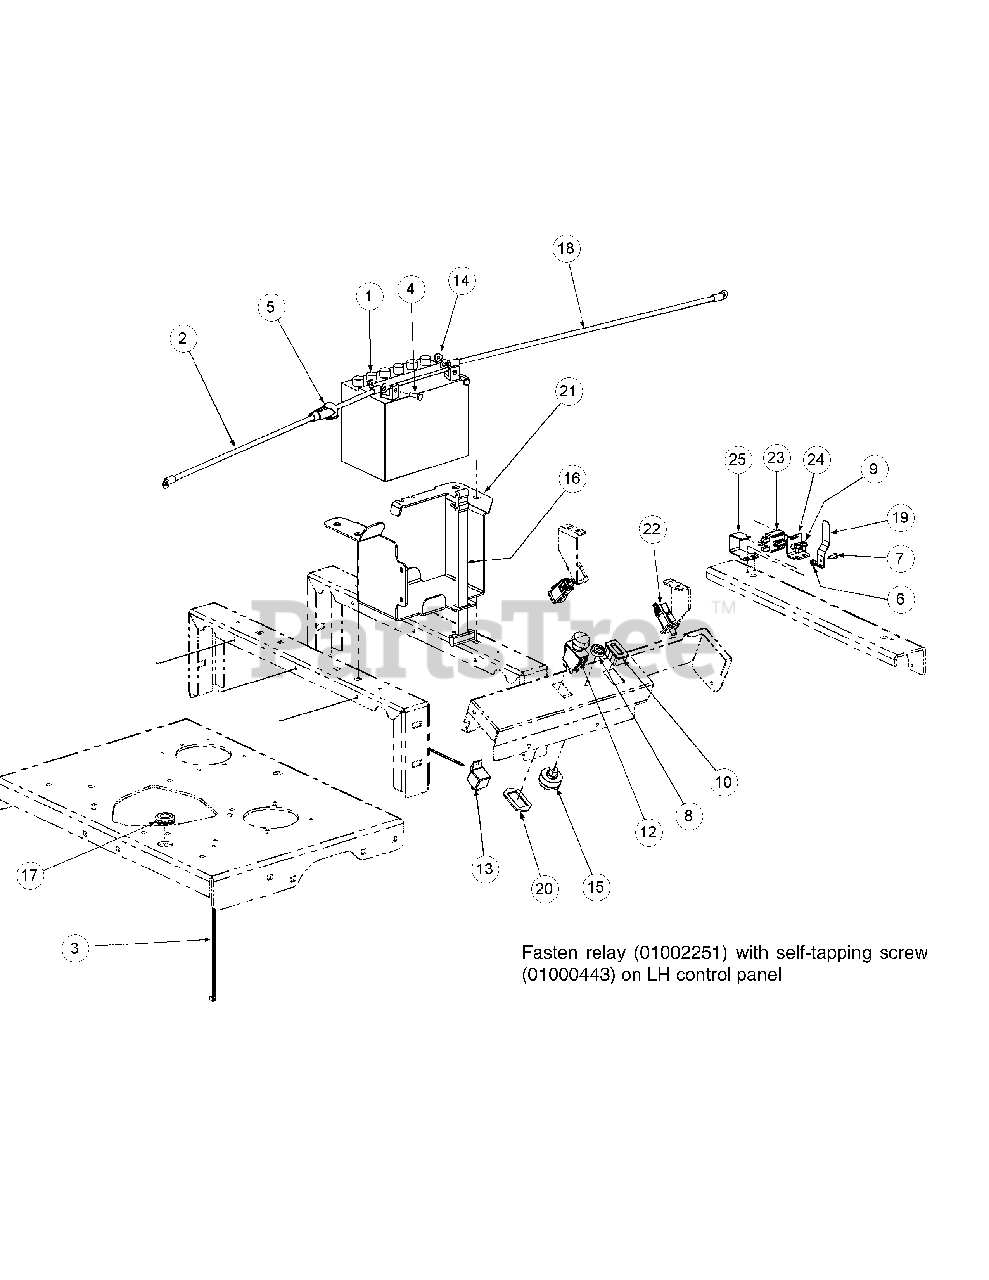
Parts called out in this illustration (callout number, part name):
1	Battery, 12V 225CCA 30 Min
2	Cable, Battery, Red, 42"
3	Tie, Cable, 3/16 x .05 x 7.4"
4	Screw, Hex, Cap, 1/4-20 x .75
5	Boot, 1" OD Rubber Battery-PST, Red
6	Lock Nut, Nylon Insert
7	Screw, Hex Washer, 10-32 x 1/2
8	Nut, W/Cap, 5/8-32 Ignition
9	Screw, TT, 1/4-20, 0.5, Hex Index Washer
10	Meter, Hour
12	Switch, Electric, PTO
13	Relay, 12V 40A
14	Lock Nut, 1/4-20
15	Switch, Ignition, 6 Pin
16	Strap, Battery
17	Grommet, .75 ID
18	Cable, Battery Red, 28"
19	Spring Retainer
20	Bracket, PTO Switch Retainer
21	Mount Bracket, Battery
22	Switch, Safety N.O./N.C.
23	Switch, Plunger
24	Bracket, Plunger Switch
25	Clamp, Plunger Switch
